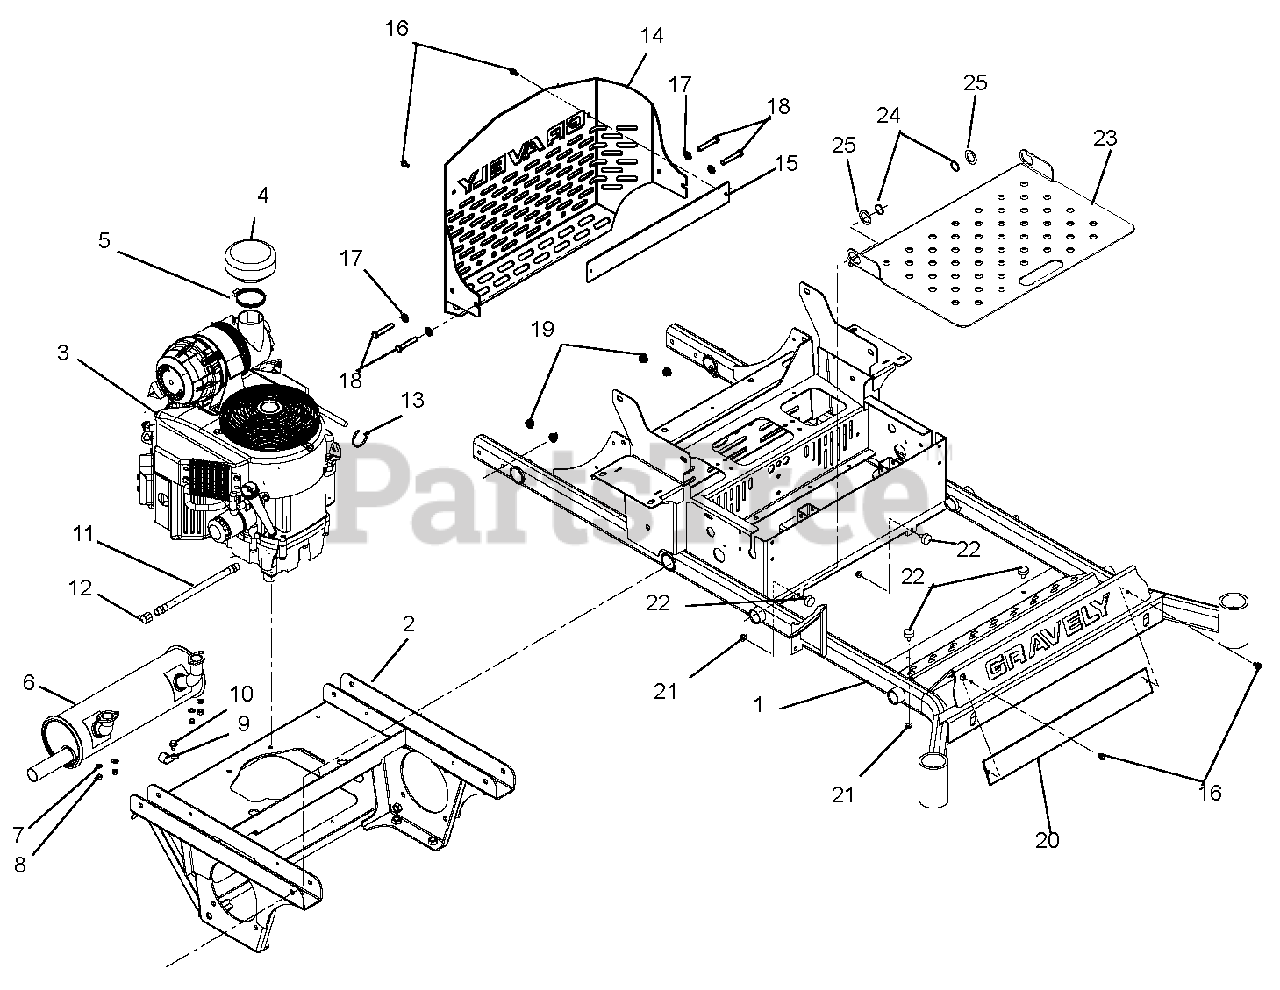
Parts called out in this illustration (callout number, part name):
1	Weldment, 52"-66" 200PT Main Frame
2	Weldment, 200PT Axle/Engine Frame
3	Engine, Kawasaki 27HP (185)
4	Rain Cap, Air Cleaner (185, 186, 187)
5	Clamp, Hose 2.75 DIA Worm (185, 186, 187)
6	Muffler, 27-31 Kawasaki (185, 186, 187)
7	Washer, Lock .31 x .078 REG YWZC
8	Nut, Locking Top M8-1.25 YWZC
10	Screw-TAP .38-16 x .50 Hex Washer Head TR YWZ
11	Hose, Hydraulic .38-11-0K M6N0-M6N0 (185, 186, 87)
12	Pipe Cap 3/8 NPT Female
13	Cable Tie LG 5-1/2
14	Weldment, Bumper, Pro-Turn 200
15	Plate, Bumper, Pro-Turn 200
16	Screw-Tap .25-20 x .50 Hex Washer Head TR YWZ
17	Washer, Flat Steel.406 x .812 x .065 YWZ
18	Bolt-Hex .38-16 x 2.25 GR5 YWZC
19	Nut, Locking Nylon-Flange .38-16 YWZC
20	Plate, Bumper Name Backer
21	Nut-Spin Lock-Flange .312-18
22	Bumper, Rubber
23	Inspection Panel
24	Ring, Retaining, External 1.00 x .078
25	Washer, Flat-Steel 1.010 x 1.505 x .062
